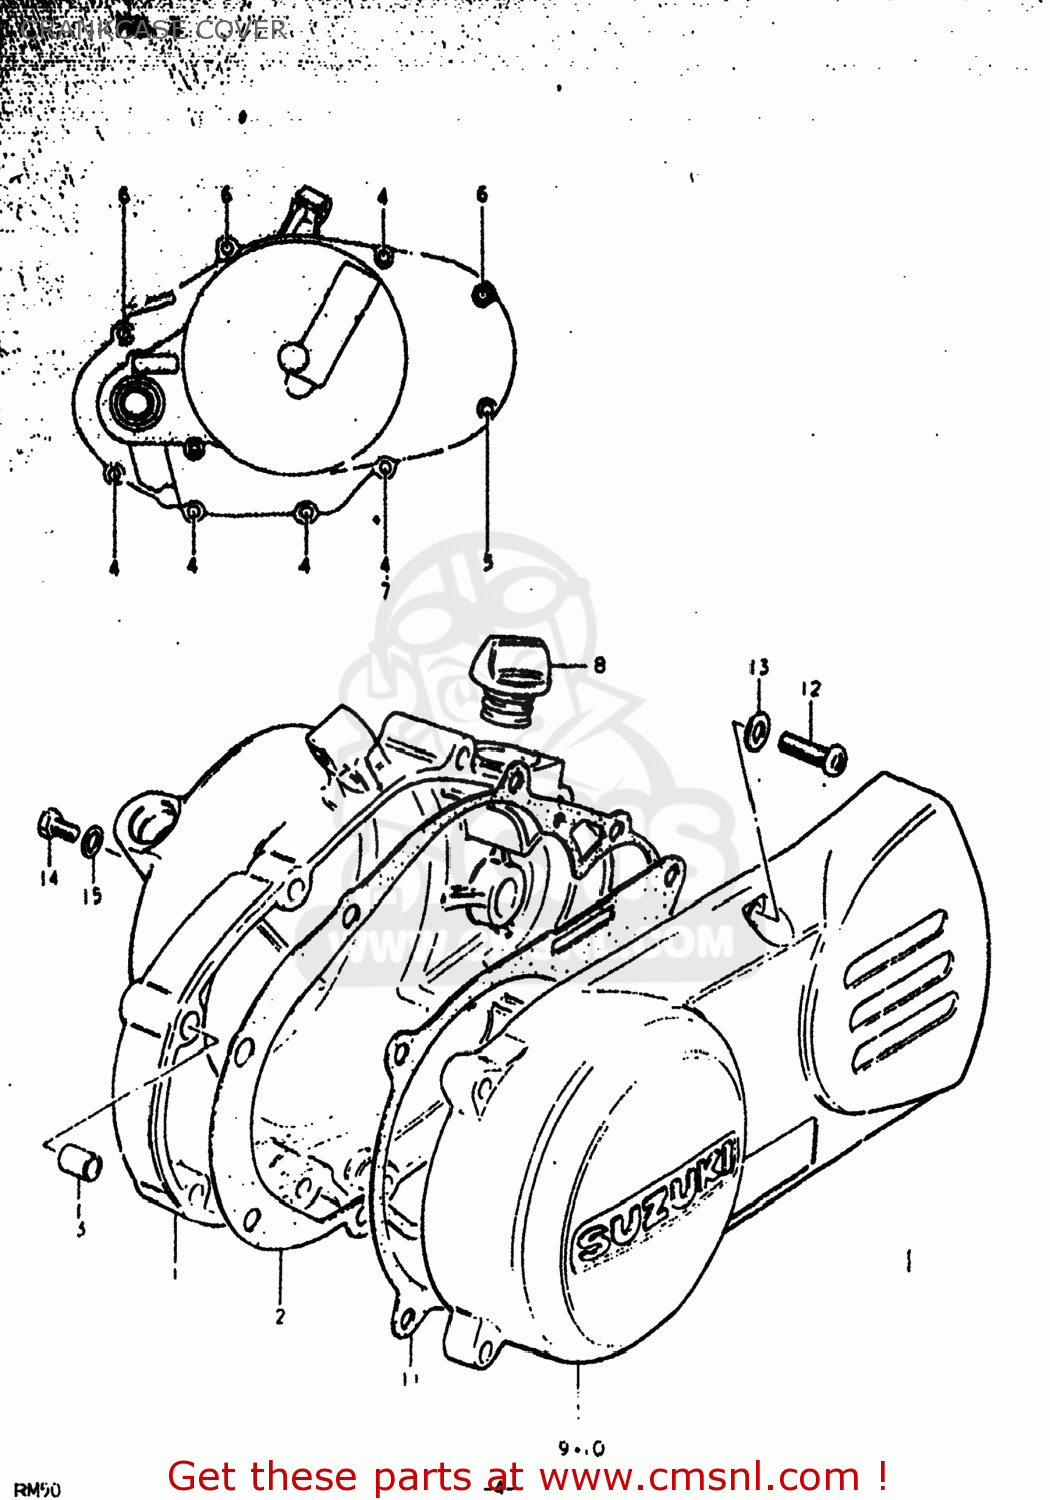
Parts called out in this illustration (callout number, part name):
1	COVER,CLUTCH
2	GASKET,CLUTCH COVER (MCA)
3	PIN
4	SCREW
5	SCREW
6	SCREW
7	GASKET(6.2X11X1).2 (NAS)
8	PLUG
9	COVER,MAGNETO
10	COVER,MAGNETO
11	GASKET,MAGNETO COVER (NAS)
12	SCREW
13	WASHER
14	SCREW(6X10)
15	GASKET(6.2X11X1) (NAS)
